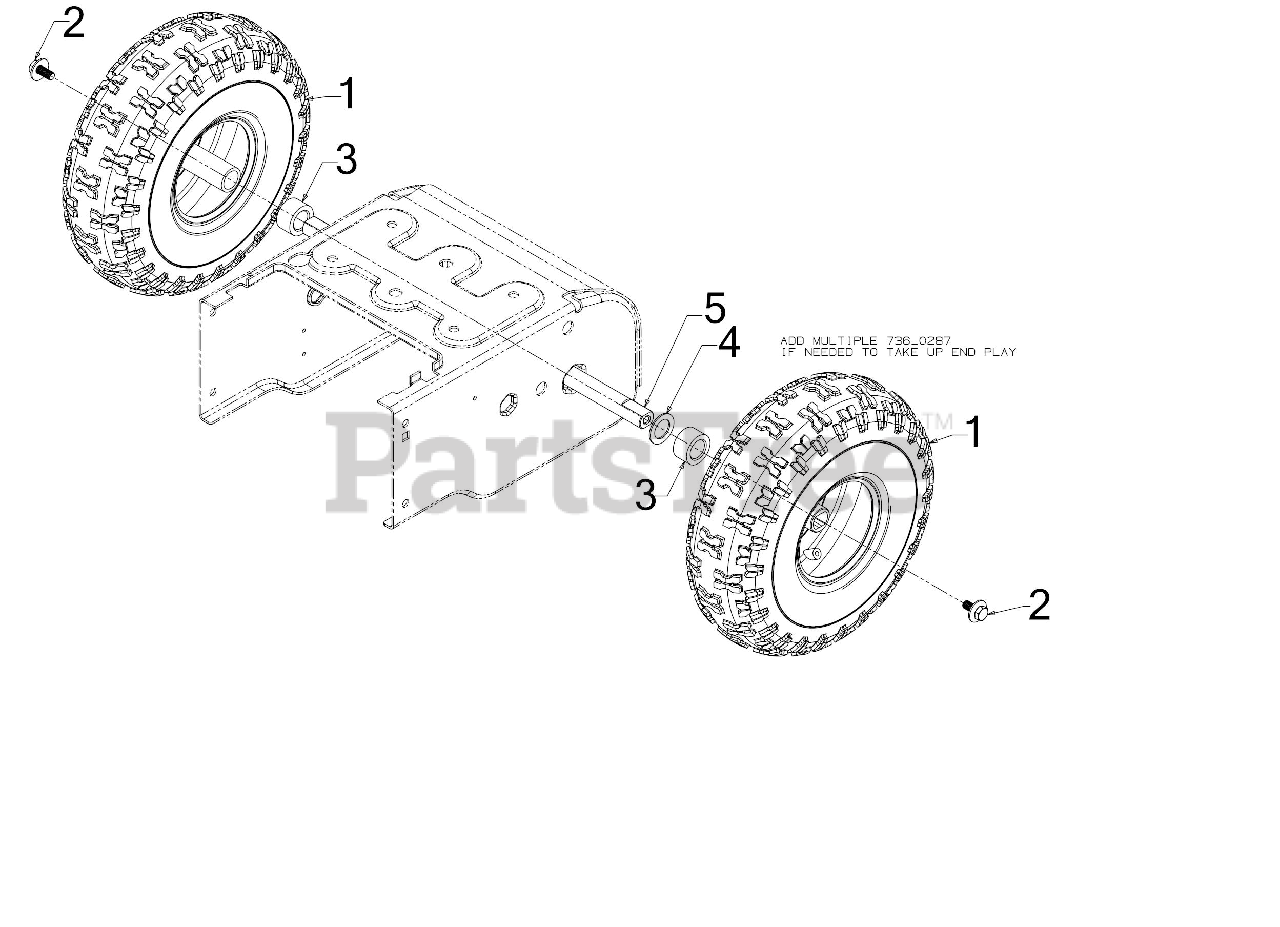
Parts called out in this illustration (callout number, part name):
1	WHEEL ASSEMBLY (10 x 4)
2	SCREW 5/16-24 x .750 GR5
3	SPACER-1.25OD x .757 ID x .690 LG
4	FLAT WASHER .793ID x 1.24OD x .060
5	AXLE-.75 OD x 17.70 LG
